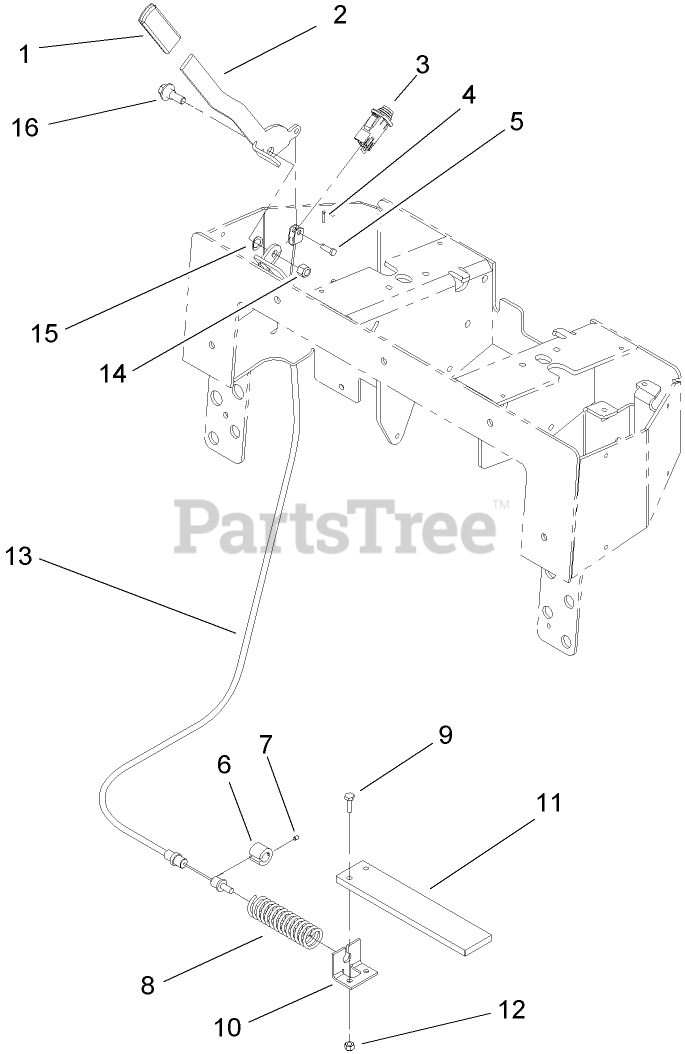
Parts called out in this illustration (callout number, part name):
1	GRIP-HANDLE
2	HANDLE-BRAKE
3	SWITCH-PLUNGER
4	PIN-COTTER
5	PIN-CLEVIS
6	Tube-Guide
7	SCREW-HSH
8	SPRING
9	SCREW-HH
10	BRACKET-MOUNTING, BRAKE
11	PLATE-BRAKE
12	NUT-LOCK, NI
13	CABLE-BRAKE
14	NUT-LOCK
15	WASHER-SPRING
16	BOLT-SHOULDER
